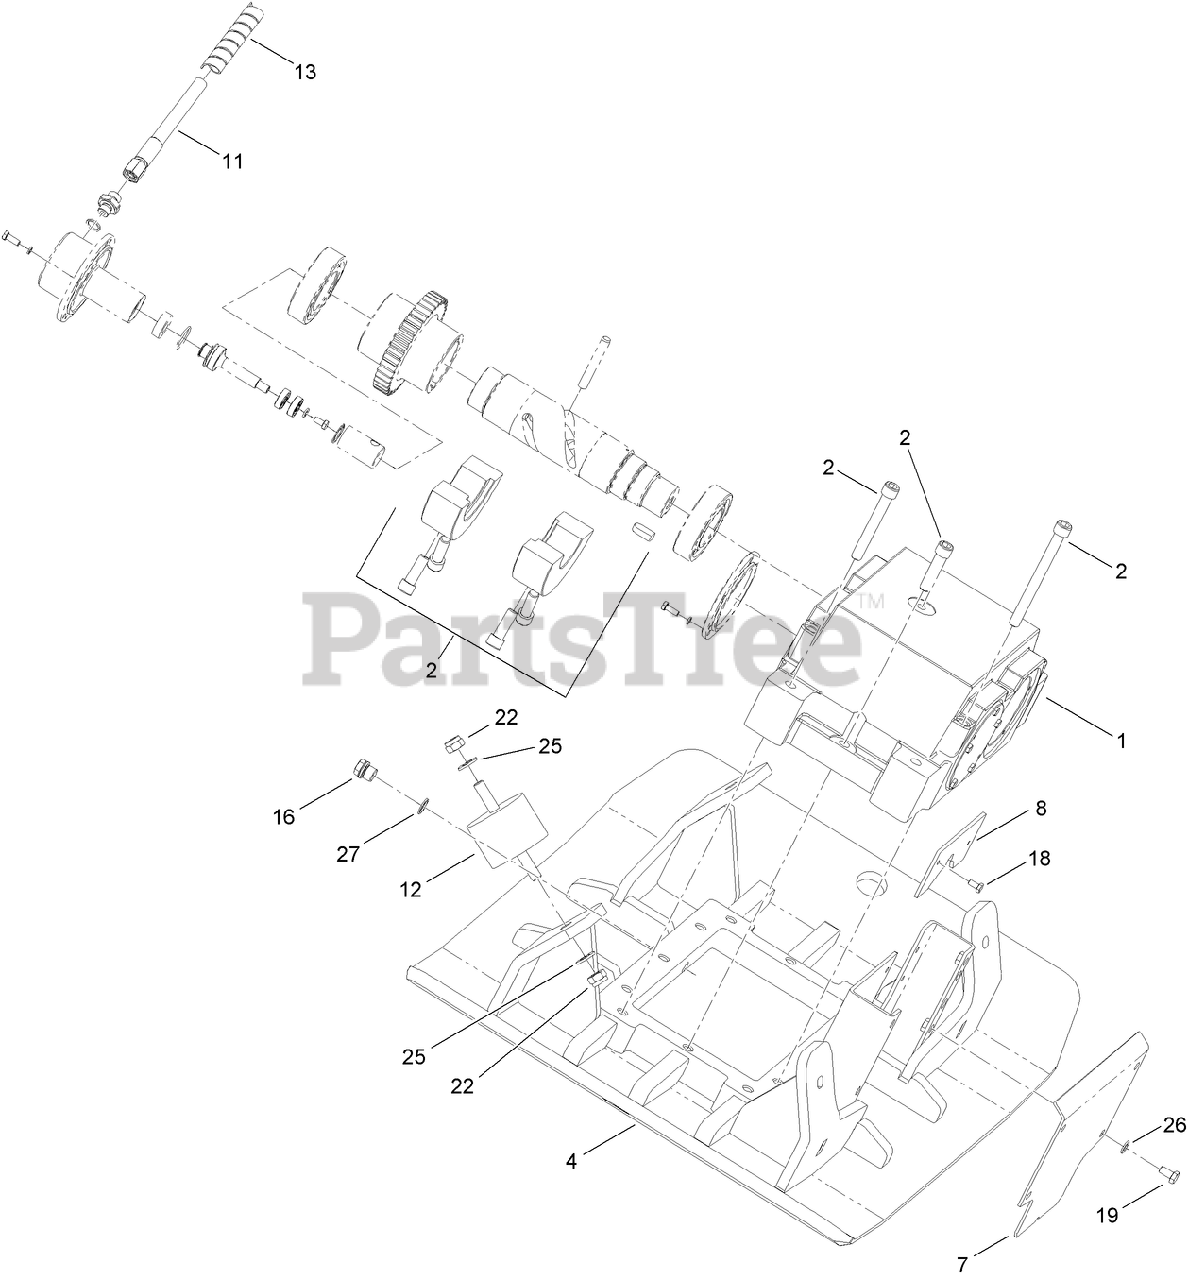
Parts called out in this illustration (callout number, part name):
1	VIBRATORY ASM
2	WEIGHT KIT
7	COVER-FRONT
8	COVER-BACK
11	HOSE-HYD
12	MOUNT-RUBBER
13	COVER-HOSE
25	WASHER
26	WASHER
